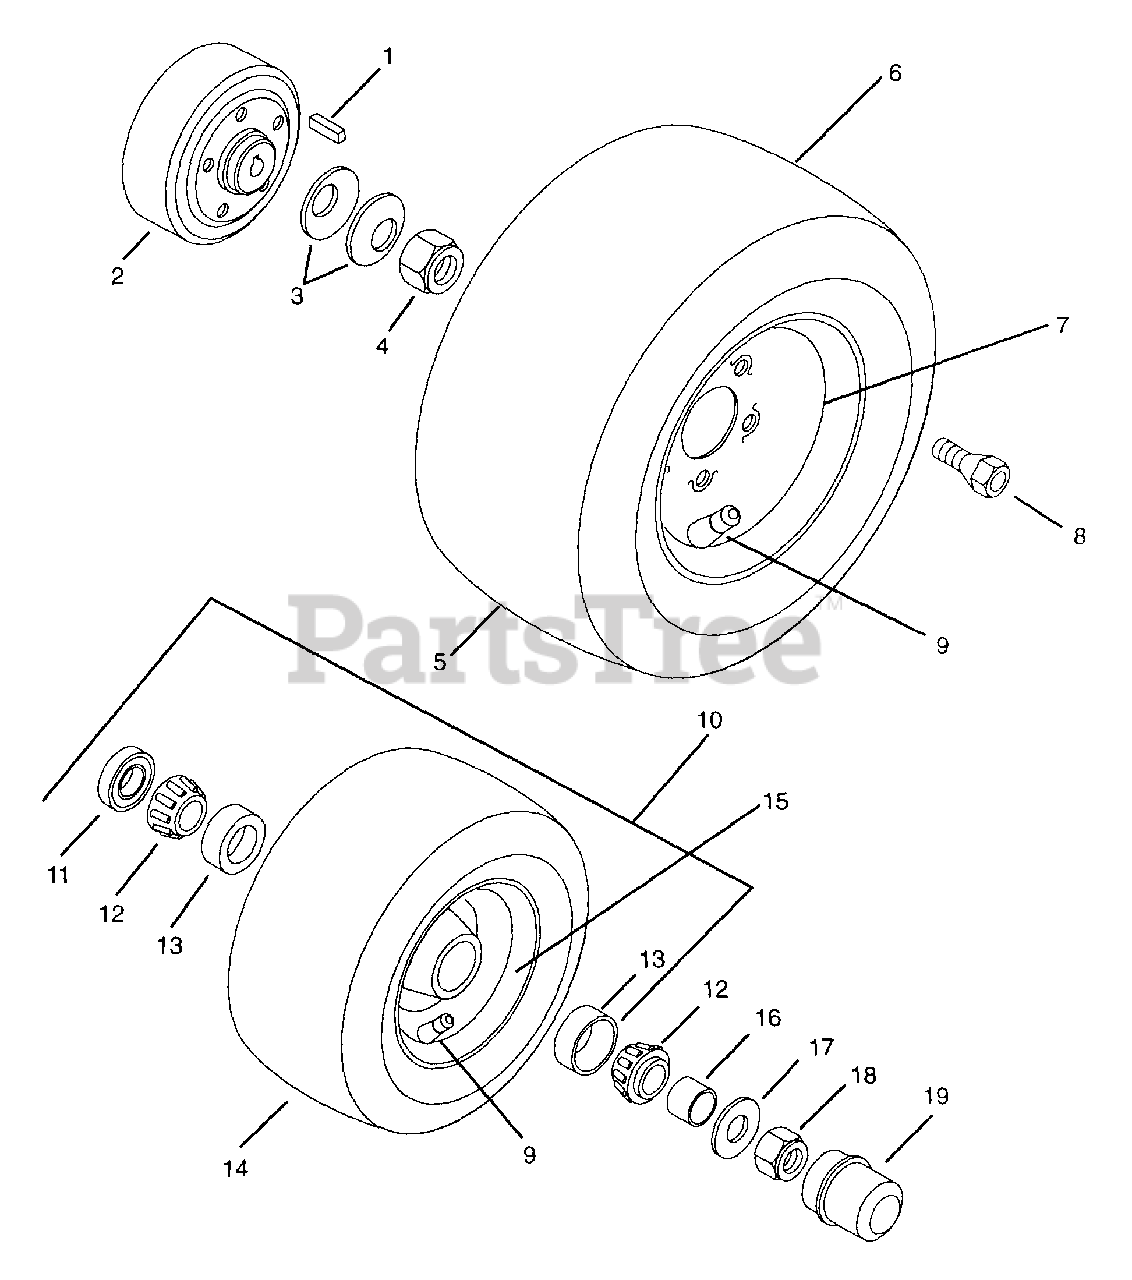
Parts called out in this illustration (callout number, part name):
1	Key-Square .312 x 2.25
2	Hub, Wheel
3	Spring-Bellville .097 x .145 x 2.00
4	Nut-Locking 1.00-14
5	Tire/Wheel Assembly 23 x 10.50-12
6	Tire, Rear 23 x 10.50-12
7	Weldment, Rim
8	Bolt .44-20 x 1.0
9	Valve Stem Assembly
10	Tire, Front Assembly
11	Seal 1.206 x 1.785 x .468
12	Bearing-Cone .750 x .61
13	Bearing-Cup 1.78 x .475
14	Tire, Front 16 x 7.50-8
14	Tire 15 x 6-6
15	Tire/Wheel Assembly 16 x 7.50-8
16	Spacer .752 x 1.000 x .500
17	Washer-Flat-Steel .656 x 1.312 x .095
18	Nut-Locking-Center .625-11
19	Dust Cap
